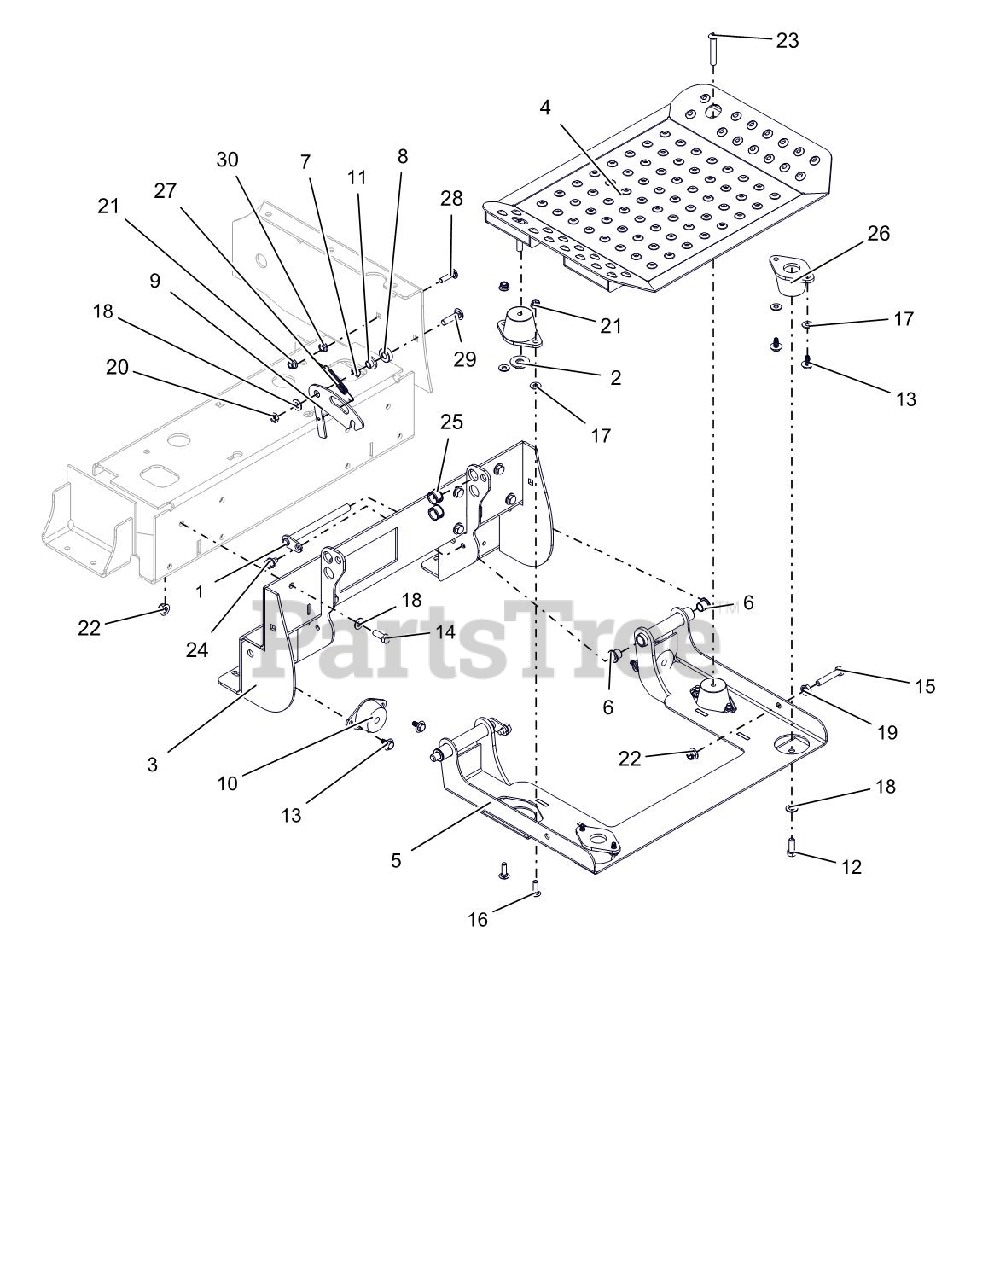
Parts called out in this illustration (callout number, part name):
1	WLDT, PIN AND LOCK Y
2	WLDMT, SEAT RETAINER
3	WLDMT, PLATFORM SUPPORT
4	WLDMT, PLATFORM TOP
5	WLDMT, PLATFORM CARRIER
6	BRG, FLG .500X.620X.500 BRNZ
7	WAVE WASHER .531X.781X.125FH
8	SPCR, .375 X 1.00 X .342
9	LATCH, PLATFORM SIDE
10	MOUNT, ENGINE, VIBRATION ISO
11	BSHG-FLG .385X.500X.875X.406
12	BLT-HEX .38-16X1.0 GR8 YZ EP30
13	BOLT, 5/16-18X.625 SLF TAP FLG
14	@BLT-HEX .38-16X1.00 GR5 YWZC
15	@BLT-HEX .38-16X2.00 GR5 YWZC
16	@BLT-RDHDSQNK .31-18X1.00 G5YZ
17	@WSHR-FL-STL.312X.734X.065 YWZ
18	@WSHR-FL-STL.406X.812X.065 YWZ
19	@NUT-SPNLK-FLG .375-16 YWZC
20	@NUT-LK-CTR-JAM .375-16 YWZC
21	@NUT-LK-NYL-FLG .31-18 YWZC
22	@NUT-LK-NYL-FLG .38-16 YWZC
23	BLT-BTHD-SOCKET .38-16X2.25FTH
24	@SCR-TAP .38-16X.50 HWH TR YWZ
25	BUSH, PANEL SNAP .687X.875X.56
26	MOUNT, ISOLATOR
27	SPRING, EXTENSION
28	@BLT-RDHDSQNK .31-18X1.25 G5YZ
29	@BLT-RDHDSQNK .38-16X1.50 G5YZ
30	@NUT-SPNLK-FLG .312-18 YWZC
